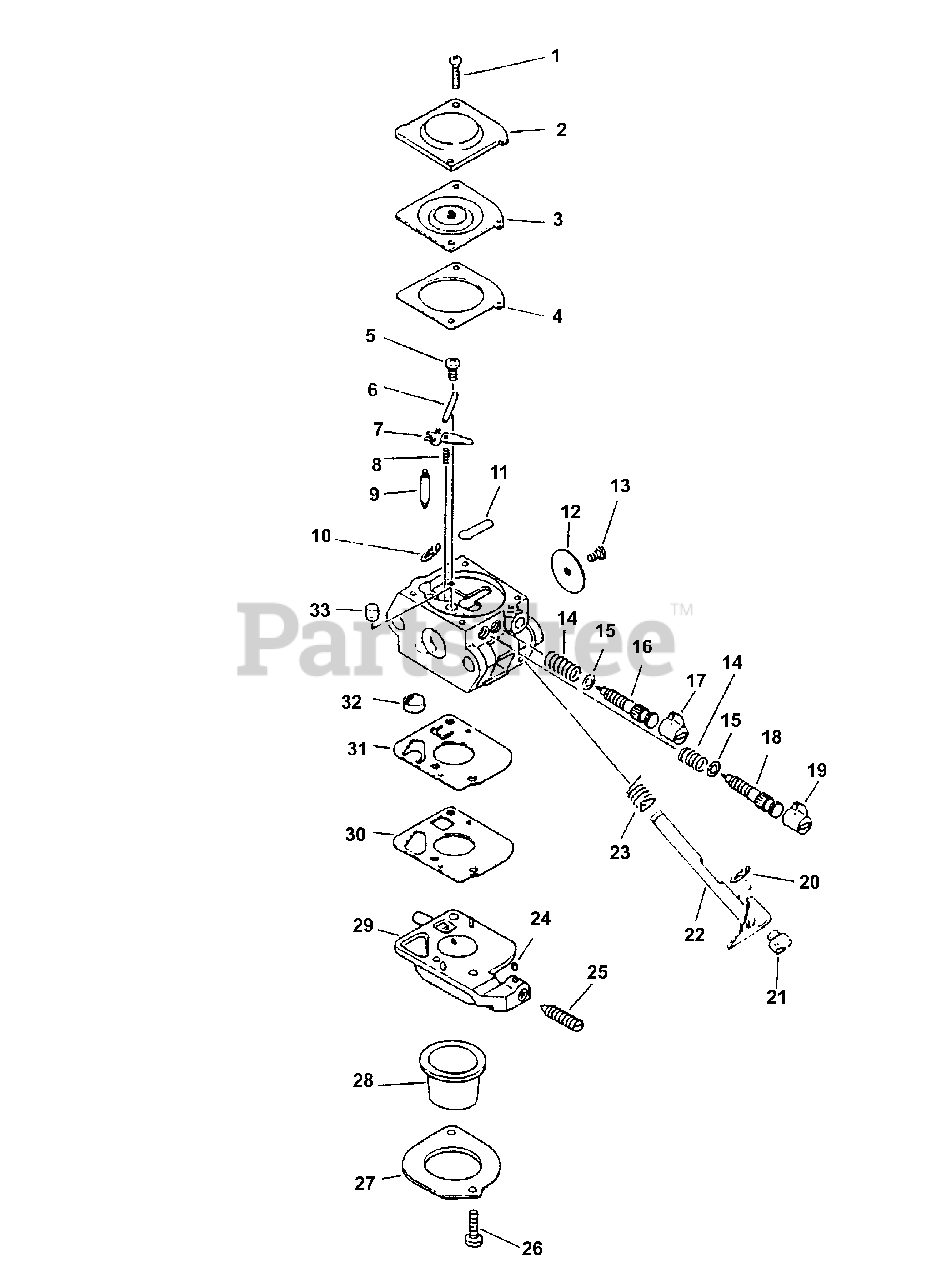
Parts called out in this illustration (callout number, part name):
2	COVER, METERING DIAPHRAGM
3	DIAPHRAGM, METERING
4	GASKET, METERING
6	PIN, METERING LEVER
7	LEVER, METERING
8	SPRING, METERING LEVER
9	VALVE, INLET NEEDLE
11	PLUG, WELCH
12	VALVE, THROTTLE
14	SPRING, NEEDLE
16	NEEDLE, IDLE
17	CAP, LIMITER - WHITE
18	NEEDLE, HIGH SPEED
19	CAP, LIMITER - RED
22	SHAFT, THROTTLE
23	SPRING, THROTTLE RETURN
24	PIECE, FRICTION
25	SCREW, IDLE ADJUST
27	RETAINER
28	BULB, PURGE
29	BODY ASSY, PURGE
32	STRAINER
33	NOZZLE, CHECK VALVE
A	REPAIR KIT
B	DIAPHRAGM/GASKET KIT
